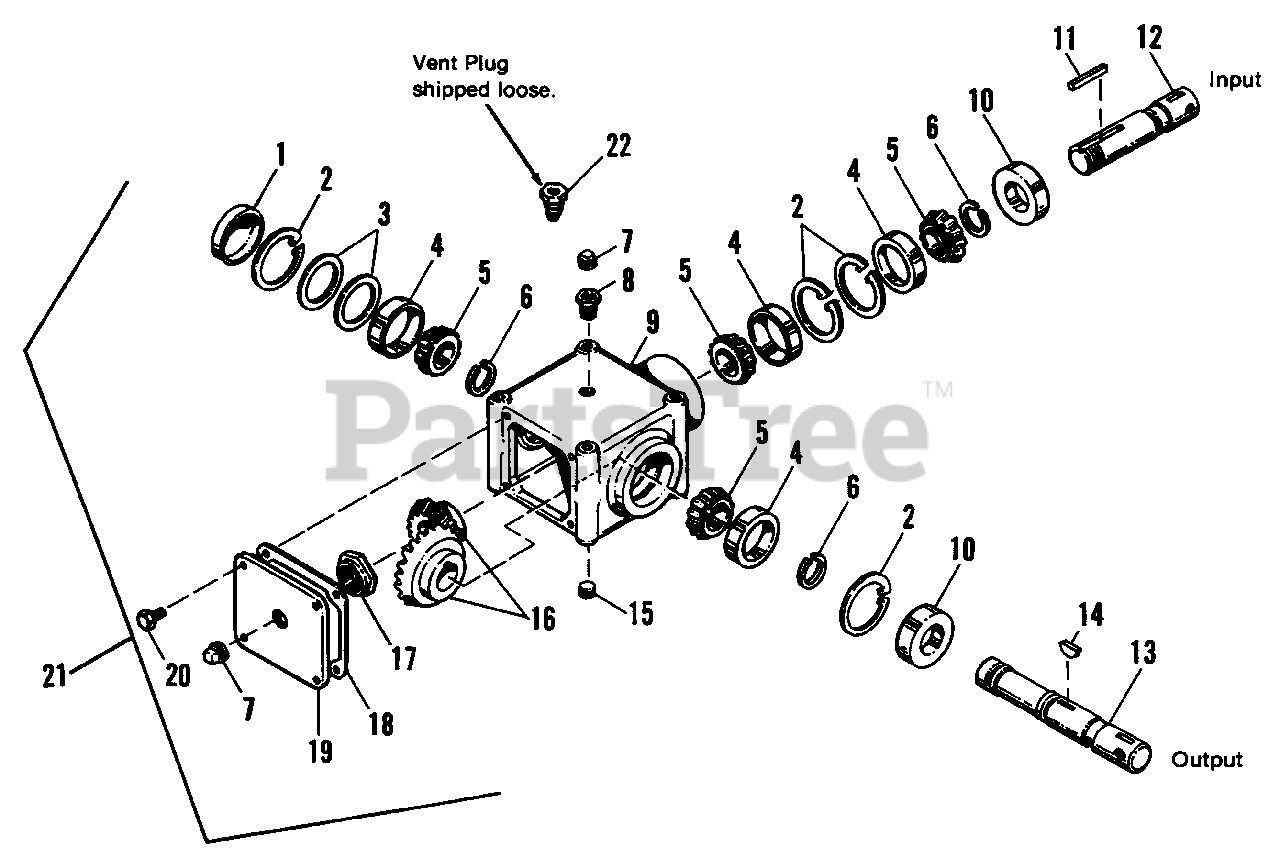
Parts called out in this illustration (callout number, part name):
2	SNAP RING
3	SHIM, Bearing
4	CUP, Bearing
5	BEARING, Cone
7	PLUG, 1/8-27 NPT
8	REDUCER BUSHING, 1/8-3/8
11	KEY, Sq., 1/4 x 1/4 x 29/32 Hard
12	SHAFT, Input
13	SHAFT, Output
14	KEY, Woodruff "A" (807) Hard
15	PLUG, Drain, 3/8-18 NPT
16	BEVEL GEAR, 17 Teeth
17	STAKE NUT, 1-18
18	GASKET, Cover
20	CAPSCREW, 5/16-18 x 5/8
21	R. ANGLE GEAR CASE ASSY.
22	VENT PLUG, 1/8-27 NPT
